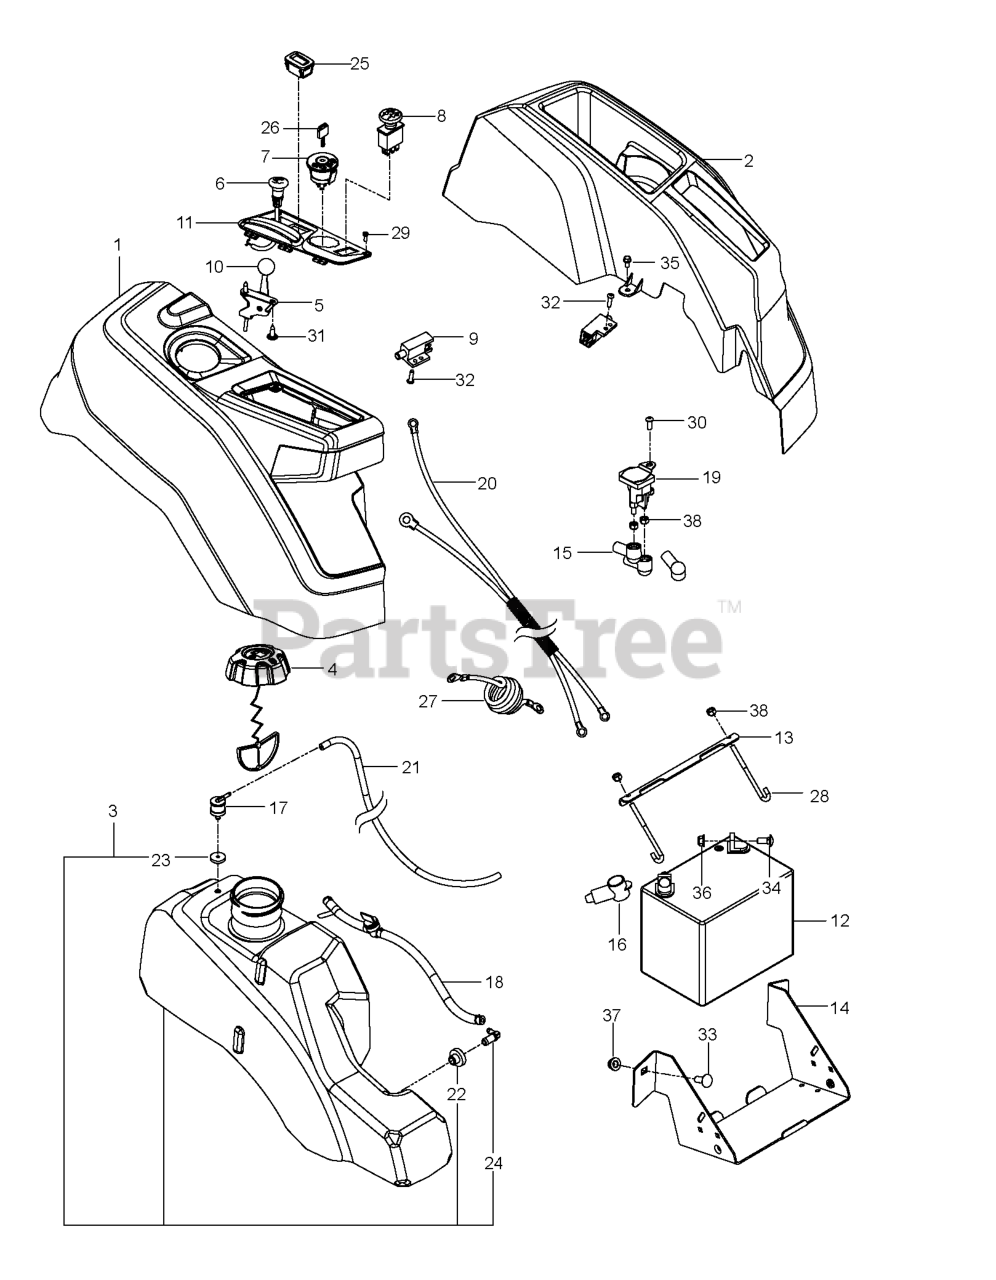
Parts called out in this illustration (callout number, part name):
1	CONSOLE.ASSY.RZ.REFRESH.RH
2	CONSOLE.LH.ASM
3	TANK.ASM3"NECK.NOCAP.NOSHDRZ18
4	FUEL CAP
4	CAP ASSY FUEL 3" GRAY
5	THROTTLE CABLE
6	CHOKE.PUSH-IN.STYLE
7	RP IGNITION SWITCH
8	RP SWITCH.PTO.TERMINAL.STD.RED
9	SWITCH.INTLK.RZ.RFRSH.BUTTON
10	KNOB.ROUND.BALL.BLACK
11	CONTROL.PANEL.RZ.REFRESH.RH
12	BATTERY WET NOT SELLABLE
13	BRACKET.PNT.MOUNT.BATTERY.EDIP
14	BOX.PNT.BATTERY.RZ.EDIP
15	TERMINAL COVER
17	VALVE.FUEL.CHECK
18	FUEL.HOSE.SHUT.OFF.ASM.10".18"
19	SOLENOID.STARTER.BRASS.PLUNGER
20	HARNESS.BTTRY.CABLE.RZ.REFRESH
21	HOSE.3/16".VAPOR.LINE.50"LGTH
22	BUSHING OUTLET T
23	GROMMET.ROV.SENTEC
24	STEM FUEL TANK
25	GUAGE.SRVCMNDR.HRMTR.
26	KEY MLD GEN DELTA
27	CABLE BATTERY POS RZ
28	HOOK.J.BATTERY
29	SCREW 6-19X.437
30	SCR 1/4-20 X 5/8 BTN SKT HD ZD
31	SCREW.PAN.HEAD.#10
32	SCREW.BUTTONHD.10-24X1/2.(2 2)
33	RHSNB 3/8C X 1
34	BOLT 5/16C X 3/4" CARRIAGE
35	SCREW
36	5/16-18 NYLOC FLANGE NUT
37	NUT 3/8-16 HEX FLG NYLOC ZD
38	NUT.1/4-20.HEX.NYLOC.ZD
